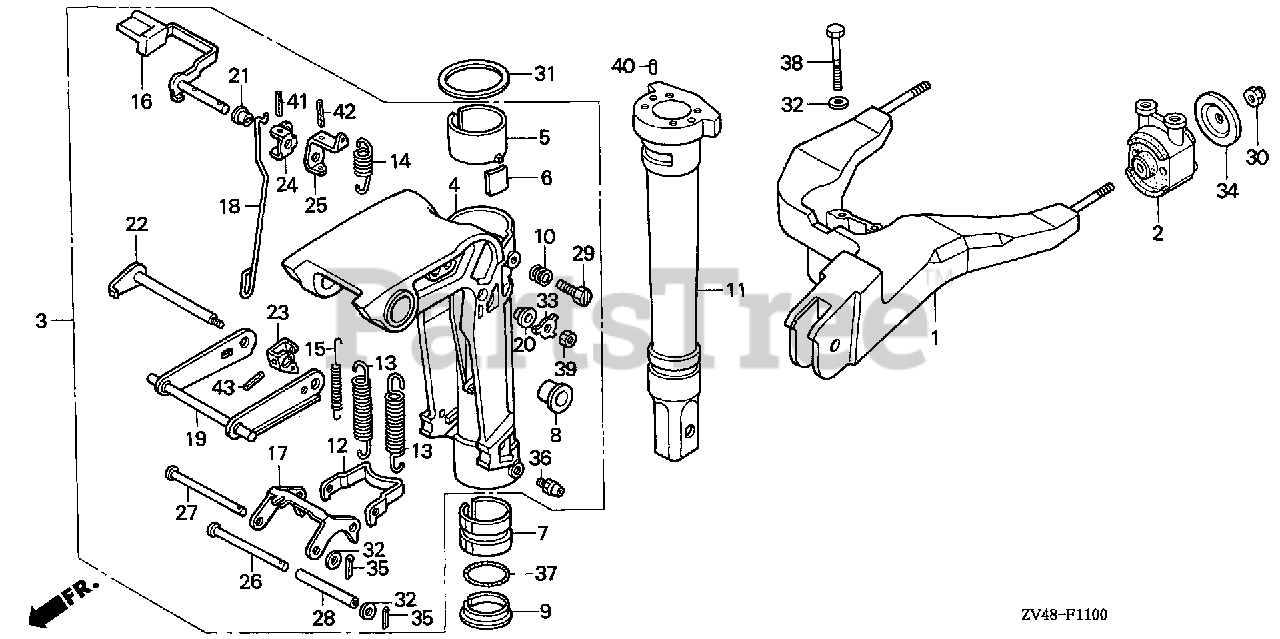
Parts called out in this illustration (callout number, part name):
1	FRAME, MOUNTING *NH282MU* (OYSTER SILVER METALLIC-U)
2	MOUNT, RUBBER (UPPER) *NH282MU* (OYSTER SILVER METALLIC-U)
3	CASE ASSY., SWIVEL *NH282MU* (OYSTER SILVER METALLIC-U)
4	CASE, SWIVEL *NH282MU* (OYSTER SILVER METALLIC-U)
5	LINER, SWIVEL CASE
6	BLOCK, FRICTION
7	BUSH, SWIVEL SHAFT
8	BUSH, SWIVEL CASE
9	COLLAR, SWIVEL CASE
10	SPRING, FRICTION ADJUSTING
11	SHAFT, SWIVEL *NH282MU* (OYSTER SILVER METALLIC-U)
12	HOOK, REVERSE LOCK
13	SPRING, REVERSE LOCK
14	SPRING, TILT LEVER
15	SPRING, TILT LINK
16	LEVER, TILT
17	ARM, REVERSE LOCK
18	ROD, RELEASE SWIVEL CASE
19	ARM, TILT
20	BUSH, TILT LEVER
21	BUSH, TILT LEVER
22	SHAFT, TILT
23	BRACKET, TILT SHAFT
24	BRACKET, RELEASE ROD
25	BRACKET, TILT LEVER
26	SHAFT, REVERSE LOCK (A)
27	SHAFT, REVERSE LOCK (B)
28	COLLAR, REVERSE LOCK
29	BOLT, SPECIAL (8X20)
30	NUT, SELF-LOCK (8MM)
31	WASHER, THRUST (51MM)
32	WASHER, PLAIN (6MM)
33	WASHER, LOCK
34	WASHER, PLAIN (8MM)
35	PIN, SPLIT (2.0)
36	NIPPLE, GREASE
37	O-RING (39.5X2.4) (ARAI)
38	BOLT, HEX. (6X60)
39	NUT, HEX. (6MM)
40	PIN, DOWEL (6X10)
41	PIN, SPRING (3.0X22)
41	PIN, SPRING (2.5X22)
42	PIN, SPRING (3.0X25)
42	PIN, SPRING (2.5X25)
43	PIN, SPRING (3.0X25)
43	PIN, SPRING (3X25)
